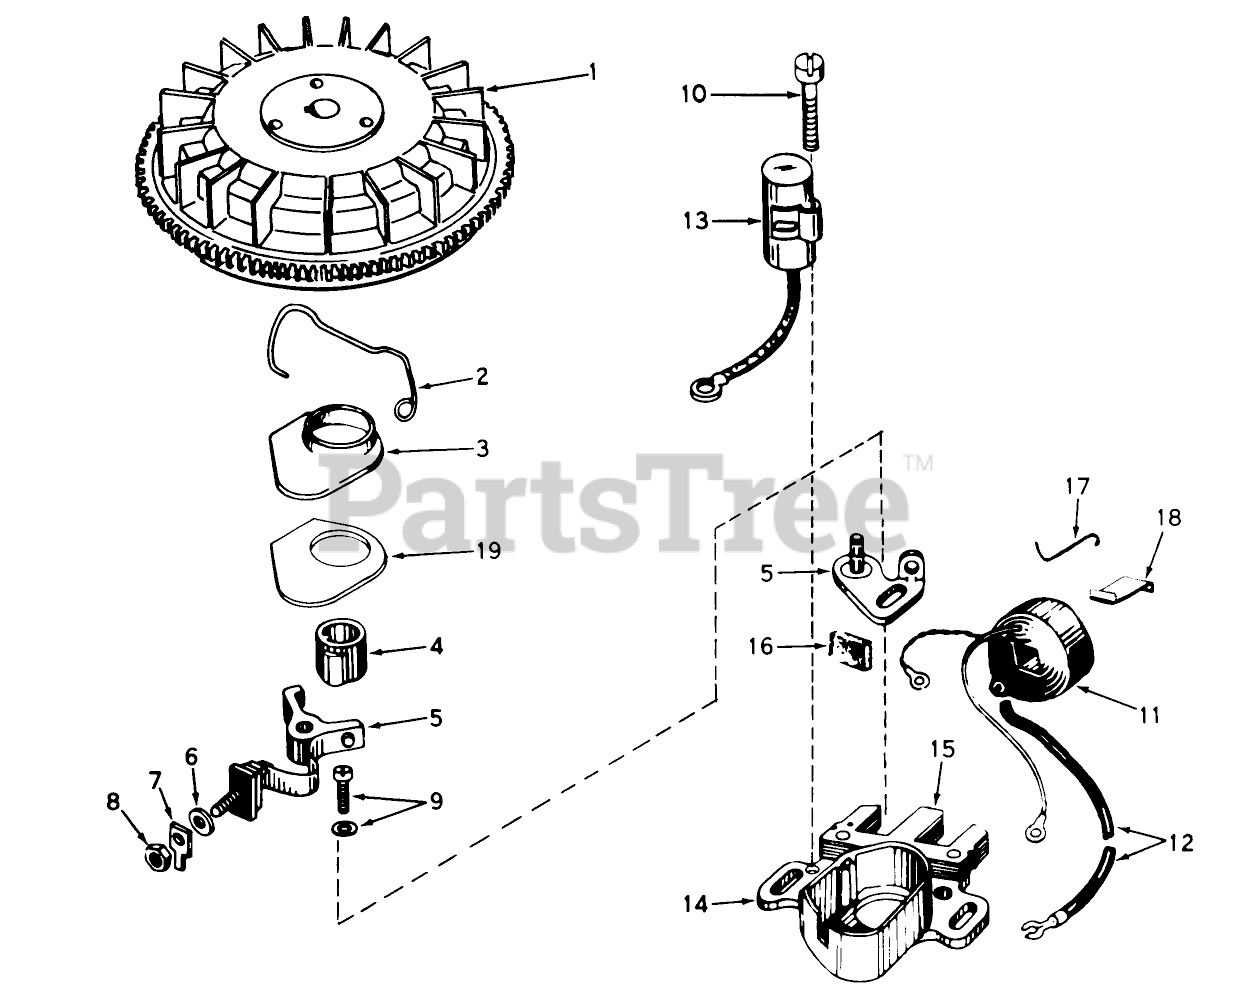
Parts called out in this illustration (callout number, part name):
1	FIywheel
1	Screw
2	Spring Breaker Box
2	Retainer
3	Cover, Dust
3	Spring-Brake
4	Cam-Breaker
4	Dog-Starter
5	Breaker Assy.
5	Spring-Dog
7	Terminal
7	Spring & Keeper Assy
8	STARTER HOUSING ASSY
9	Breaker Screw
9	Rope Starter
10	Condenser Screw
10	Assy., Starter
11	Coil Assy. (Incl. No. 12)
11	Centering
12	Wire, Lead
13	Condenser
14	Core & Plate
15	Stator Assy. (Incl. Nos. 5 thru 14, 16, 17 & 18)
16	Felt,Cam Wiper
17	Clip, Coil
18	Spring Coil Wedge
19	Gasket Dust Cover
